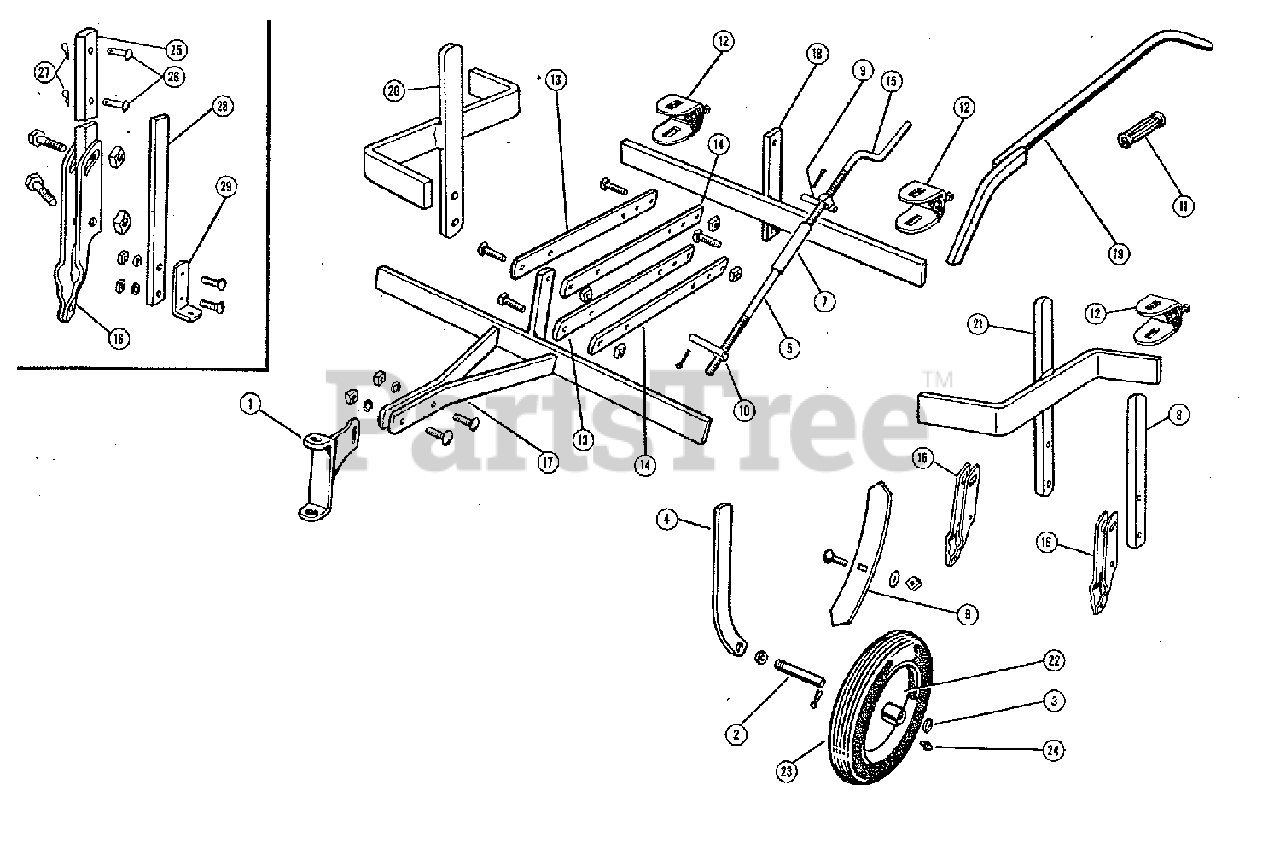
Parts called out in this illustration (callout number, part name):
1	END, Draw Bar
2	WHEEL SPINDLE, Guage
3	WHEEL WASHER, Guage
4	WHEEL STANDARD, Guage
5	MEMBER, Lower Screw
6	CULTIVATOR STEEL, w/Bolt
7	COUPLING, Adjustment
8	TOOL STANDARD, Short
9	NUT, Upper Adjustment
10	NUT, Lower Adjustment
11	HANDLE, Rubber Grip
12	CLAMP, Shank
13	BAR, Parallel (Right), Unthreaded
14	BAR, Parallel (Left), Threaded
15	MEMBER, Upper Screw
16	TOOL HOLDER ASSEMBLY
17	DRAW BAR ASSEMBLY
18	TOOL BAR ASSEMBLY
19	TOOL HANDLE ASSEMBLY
20	FRAME ASSEMBLY, R.H. Tool
21	FRAME ASSEMBLY, L.H. Tool
22	WHEEL, Complete (Less Tire)
27	CLIP, Spring
28	STANDARD, Tool
29	HOLDER, Tool
